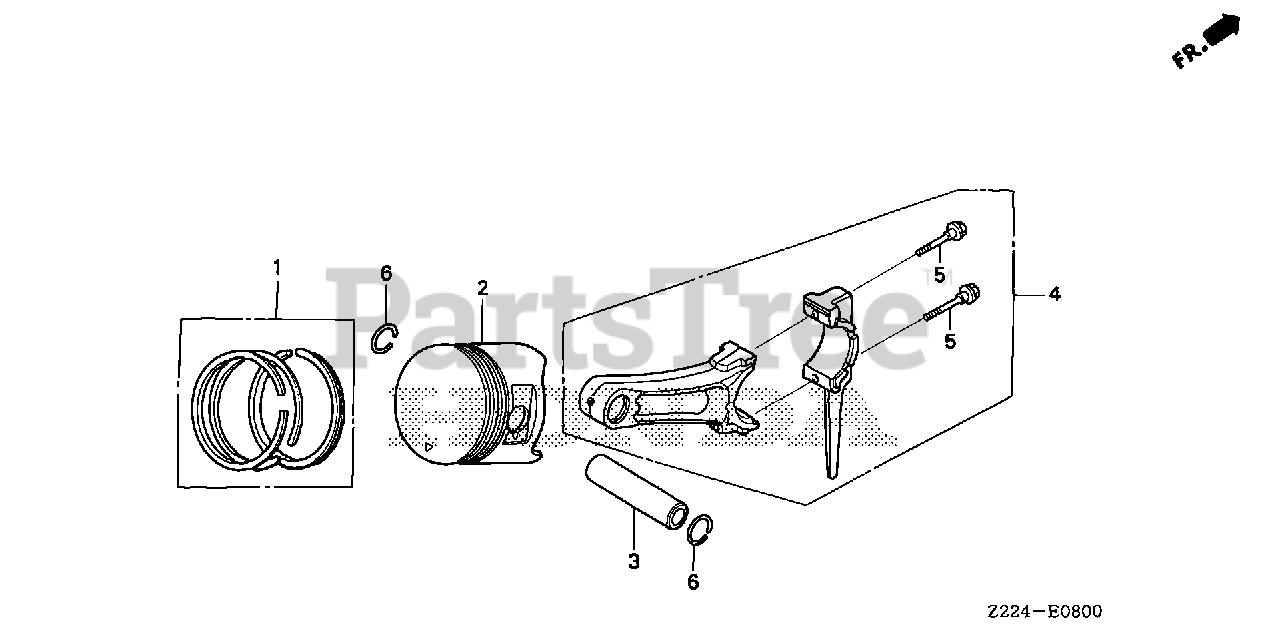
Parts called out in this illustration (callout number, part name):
1	RING SET, PISTON (STD) (TEIKOKU)
1	RING SET, PISTON (0.25) (TEIKOKU)
1	RING SET, PISTON (0.50) (TEIKOKU)
1	RING SET, PISTON (0.75) (TEIKOKU)
2	PISTON (STD)
2	PISTON (0.25)
2	PISTON (0.50)
2	PISTON (0.75)
3	PIN, PISTON
4	ROD ASSY., CONNECTING (0.25 LOWER SIZE)
4	ROD ASSY., CONNECTING (STD)
5	BOLT, CONNECTING ROD
6	CLIP, PISTON PIN (20MM)
